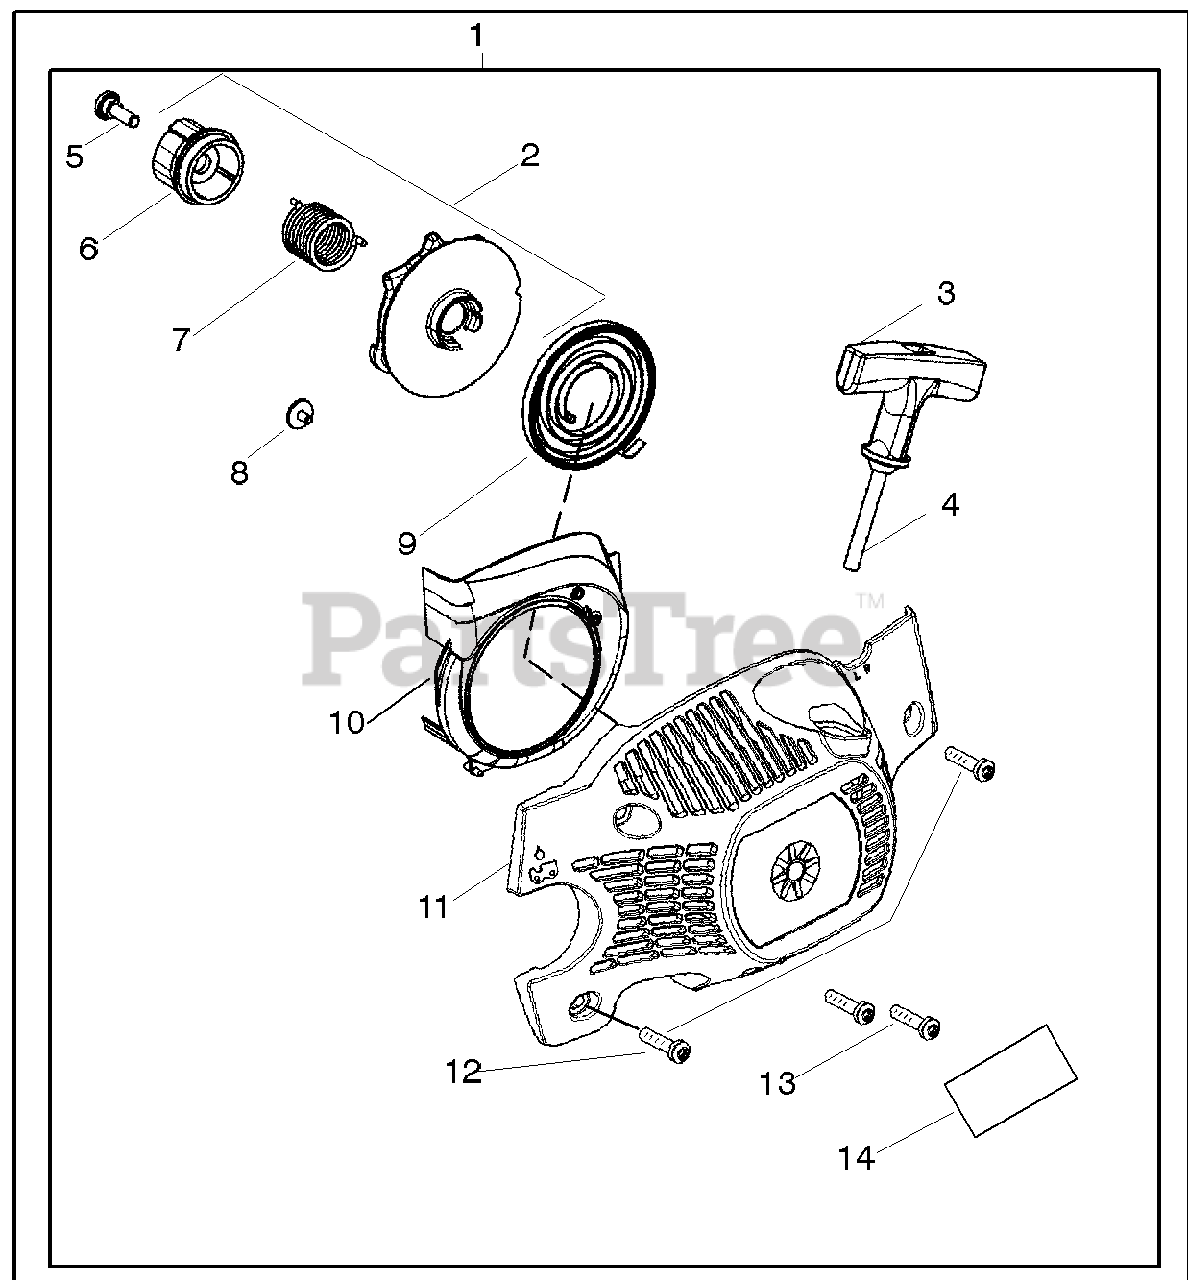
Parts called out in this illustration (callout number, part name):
1	Kit-Fan Hsg / Starter
2	Kit-Starter EPS
3	Handle-Starter
5	Screw-shoulder
7	Spring-EPS
9	Spring-Starter
10	Baffle- Air
11	Assy-Fan Hsg. w/eyelet
14	Decal-Fan Housing
